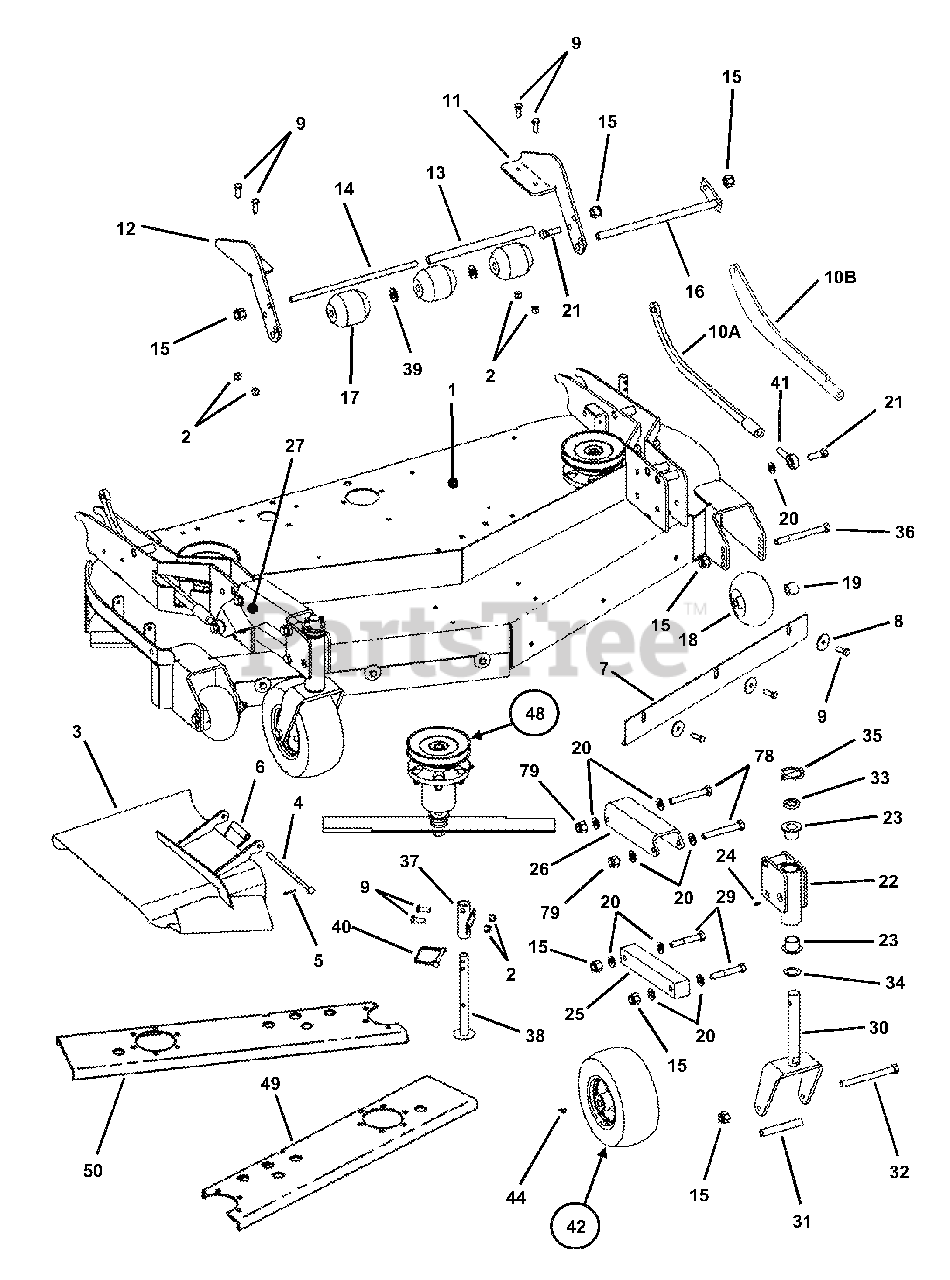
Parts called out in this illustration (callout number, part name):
1	WELDMENT, 61" Deck- Adjustable Height
2	NUT, 3/8-16 HEX NYLON LOCK
3	DEFLECTOR, Chute 61" Euro (Weldment)
4	PIN, Chute Hinge
5	PIN, 3/32 x 1" Cotter
6	SPRING, Chute
7	BAFFLE, Front
8	WASHER, 13/32 x 1-1/2" Flat
9	BOLT, 3/8-16 X 1" GD5 CZ
10A	LINK, Height of Cut
10B	LINK, Height of Cut, Heavy Duty
11	MOUNT, Roller Left Hand
12	MOUNT, Roller Right Hand
13	TUBE, Roller
14	PIN, Roller
15	NUT, 1/2-13 Hex Nyloc
16	WELDMENT, Shaft
17	ROLLER, Low Density Polyethylene
18	WHEEL, Gage
19	SPACER, Gage Wheel
20	WASHER, 1/2" Flat
21	BOLT, 1/2-13 X 1-1/2 GD5 CZ
22	TUBE, Caster (Weldment)
23	BUSHING, Caster
24	FITTING, Lube 1/4-28 Straight
25	ARM, Lower Caster
26	ARM, Caster Support Left Hand
27	ARM, Caster Support Right Hand
29	BOLT, 1/2-13 X 3" GD5 CZ
30	WELDMENT, Caster
31	SLEEVE, Axle
32	BOLT, 1/2-13 X 5-1/2" GD5 YZ
33	SPACER, 1" x 1 3/8 x .30" (PM)
34	BUSHING, Machine
35	PIN, 7/16" HD Lynch
36	BOLT, 1/2-13 X 5 GD5 YZ
37	TUBE, Jack Stand (Weldment)
38	WELDMENT, Jack Stand
39	WASHER, 5/8" Flat
40	PIN, 5/16" Lynch
41	BALLJOINT, 1/2-20
42	ASSEMBLY, Wheel/Tire
44	FITTING, Grease 1/4"
48	GROUP, Spindle
49	STIFFENER, 61" Deck, Left Hand
50	STIFFENER, 61" Deck, Right Hand
78	SCREW, 1/2-20 x 4-1/2" Hex Head Cap, Grade 5
79	NUT, 1/2-20 Hex Nyloc
